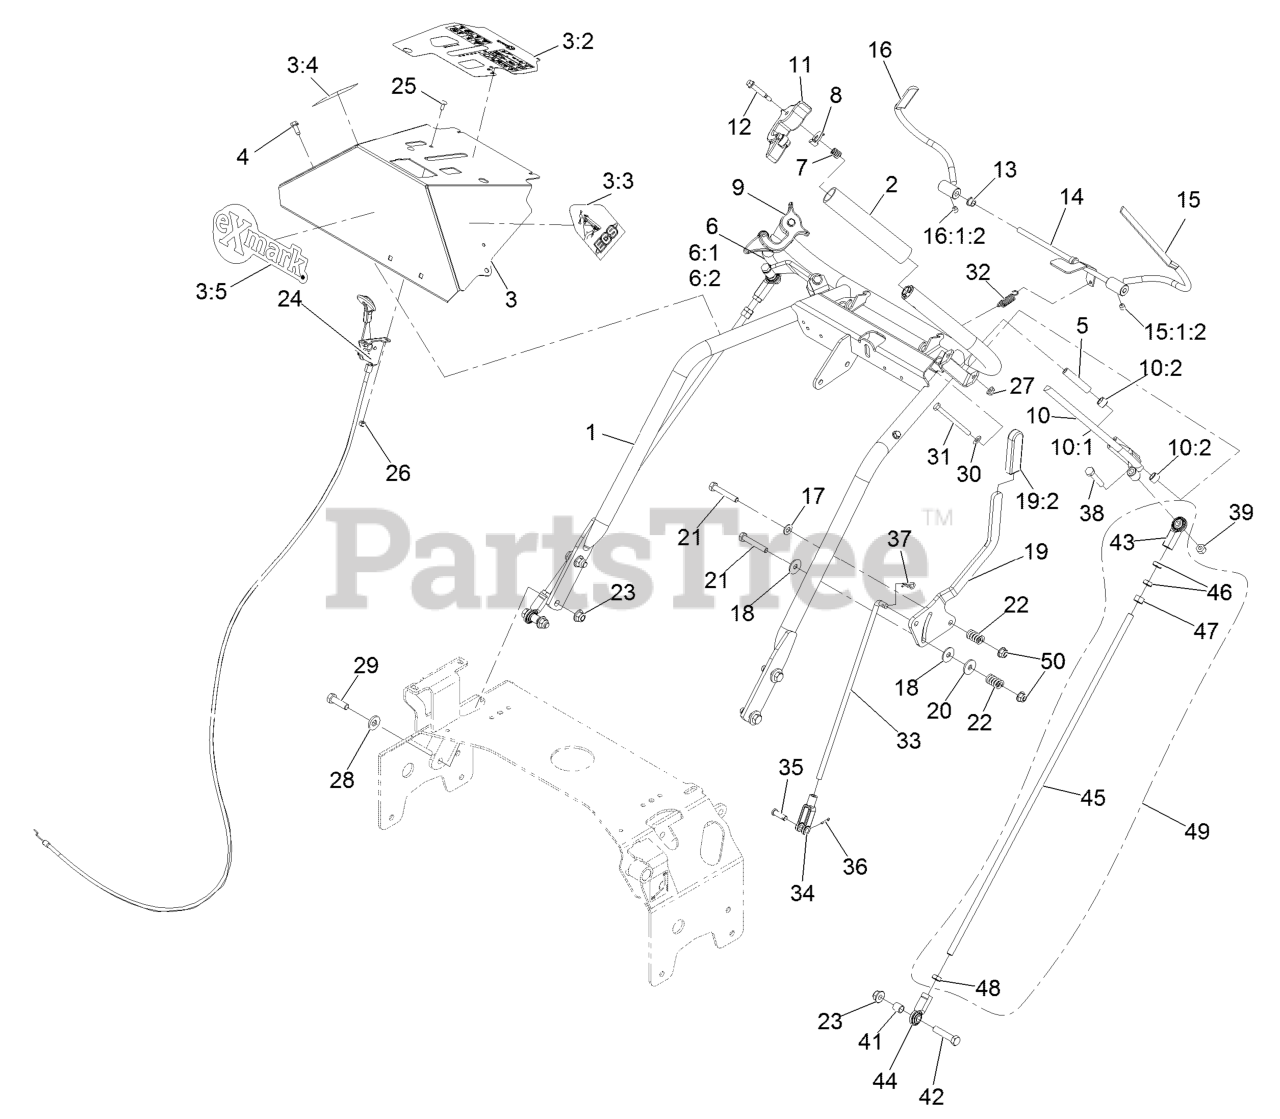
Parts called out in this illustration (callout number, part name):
1	WELD, HANDLE
2	GRIP-BAR, HANDLE
3	ASM, CONSOLE W/ DECALS
3:2	DECAL-CONSOLE TTX EFI
3:3	DECAL,LH ECS INSTRUCTION
3:4	DECAL,RH ECS INSTRUCTION
3:5	DECAL,EXMARK LOGO
4	SCREW-HWH
5	BUSHING-LEVER, DRIVE
6	DRIVE LEVER-ASM, RH
6:1	WLD,RH DRIVE LEVER
6:2	BUSHING-SLEEVE
7	SPRING-TANK, FUEL
8	LATCH, ECS
9	ASM,LATCH RH THUMB
10	DRIVE LEVER-ASM, LH
10:1	WLD,LH DRIVE LEVER
10:2	BUSHING-SLEEVE
11	ASM,LATCH LH THUMB
12	SCREW-SHOULDER
13	BUSHING-NYLON
14	WLD,OPC LEVER AXLE
15	WLD,LH OPC LEVER
15:1:2	SCREW-SET
16	WLD,RH OPC LEVER
16:1:2	SCREW-SET
17	WASHER-PLAIN
18	WASHER-FRICTION
19	LEVER, SHIFT W/GRIP
19:2	GRIP-HANDLE, STEERING
20	WASHER-FRICTION
21	SCREW-HH
22	SPRING-COMPRESSION
23	NUT-HF, NI
24	CONTROL-THROTTLE
25	BOLT-CARR
26	NUT-LOCK, NI
28	WASHER-BELLEVILLE
29	SCREW-HH
30	WASHER-FLAT
31	SCREW-HH
32	SPRING-EXTENSION
33	ROD,SPEED CONTROL
34	YOKE-ADJUSTABLE
35	PIN-CLEVIS
36	PIN-COTTER
37	PIN-COTTER
38	SCREW-HH
39	NUT-LOCK, NI
41	SPACER-TUBE, PUMP LINK
42	SCREW-HH
43	JOINT-BALL, END
44	JOINT-BALL END, LH
45	LINK,DRIVE (PLTD)
46	NUT-HJ
47	NUT-HEX
48	NUT-HEX JAM, LH
49	DRIVE LINK ASM
50	NUT-HF, NI
